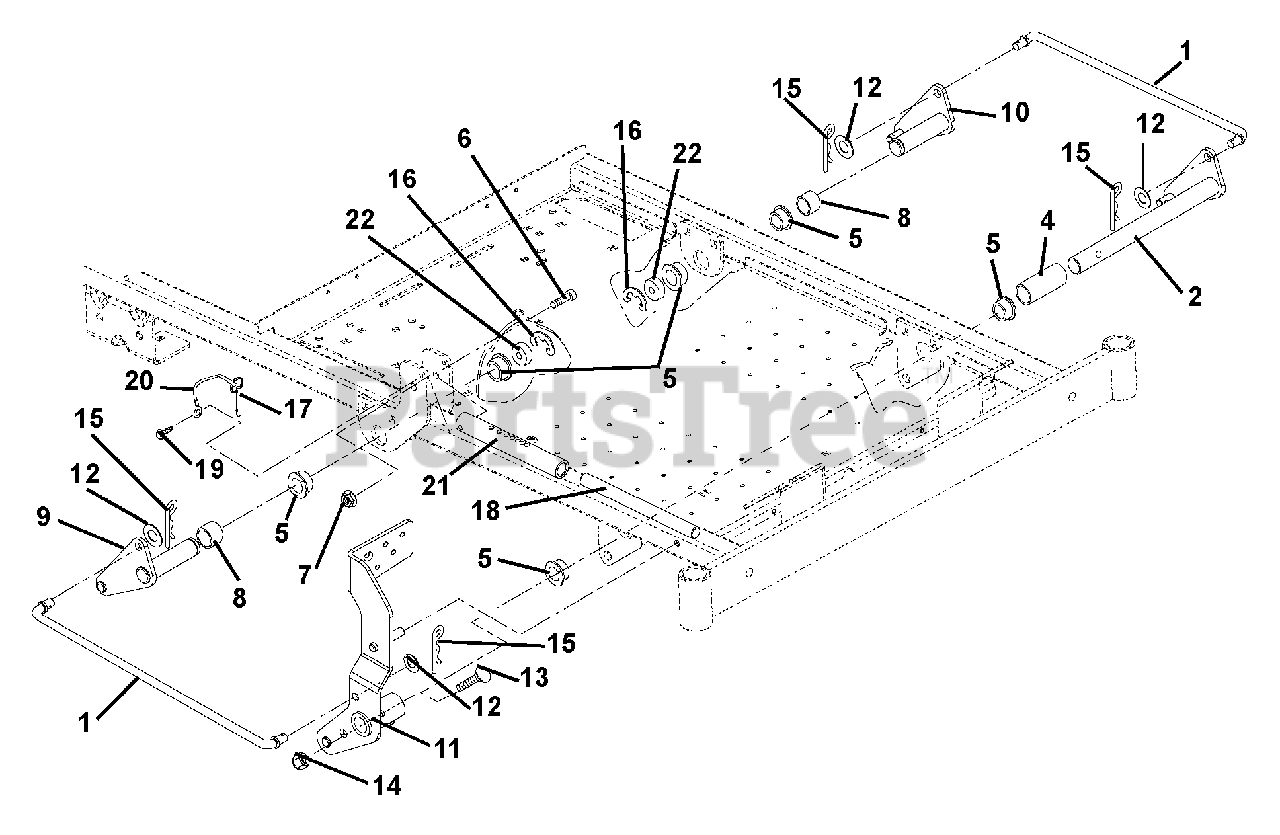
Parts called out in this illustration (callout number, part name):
1	Rod, Lift
2	Weldment, Front Lift
3	Trunnion
4	Bushing, Front
5	Bushing-Flange 1.00 x 1.12 x .62 x 1.50 Bronze
6	Bolt, Socket Head Shield .31 x 18 x 2.00
7	Nut, .31-18 Flange Nyloc
8	Bushing, Rear
9	Weldment, Lift, Rear Right Hand
10	Weldment, Lift, Rear Left Hand
11	Weldment, Foot Pedal
12	Washer-Flat-Steel .531 x 1.06 x .095
13	Bolt, Hex .38-16 x 2.00 Grade 5
14	Nut .38-16 Flange Nyloc
15	Pin, Hair External
16	Ring, Retaining .82 x 1.50 x .05
17	Pin, Spring Ball .375 O.D. x 1.50
18	Rod, Lift
19	Screw-Tapping .250-20 x .37 Hex Washer Head
20	Hood Cable
21	Tube, Lift Stop
22	Spacer, Rear Lift
